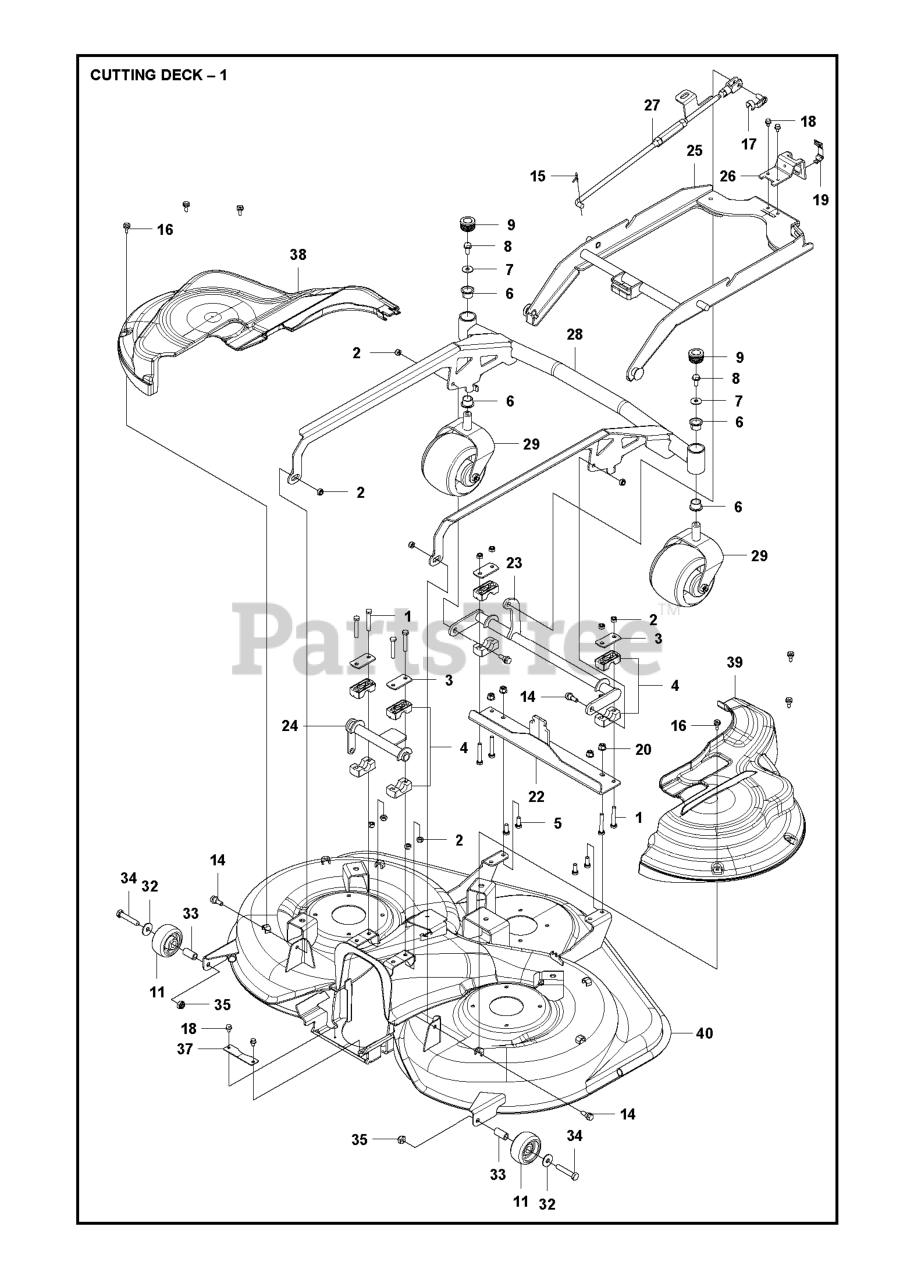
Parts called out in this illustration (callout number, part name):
2	LOCKNUT M8
11	WHEEL
20	NUT FLANGE
35	NUT
